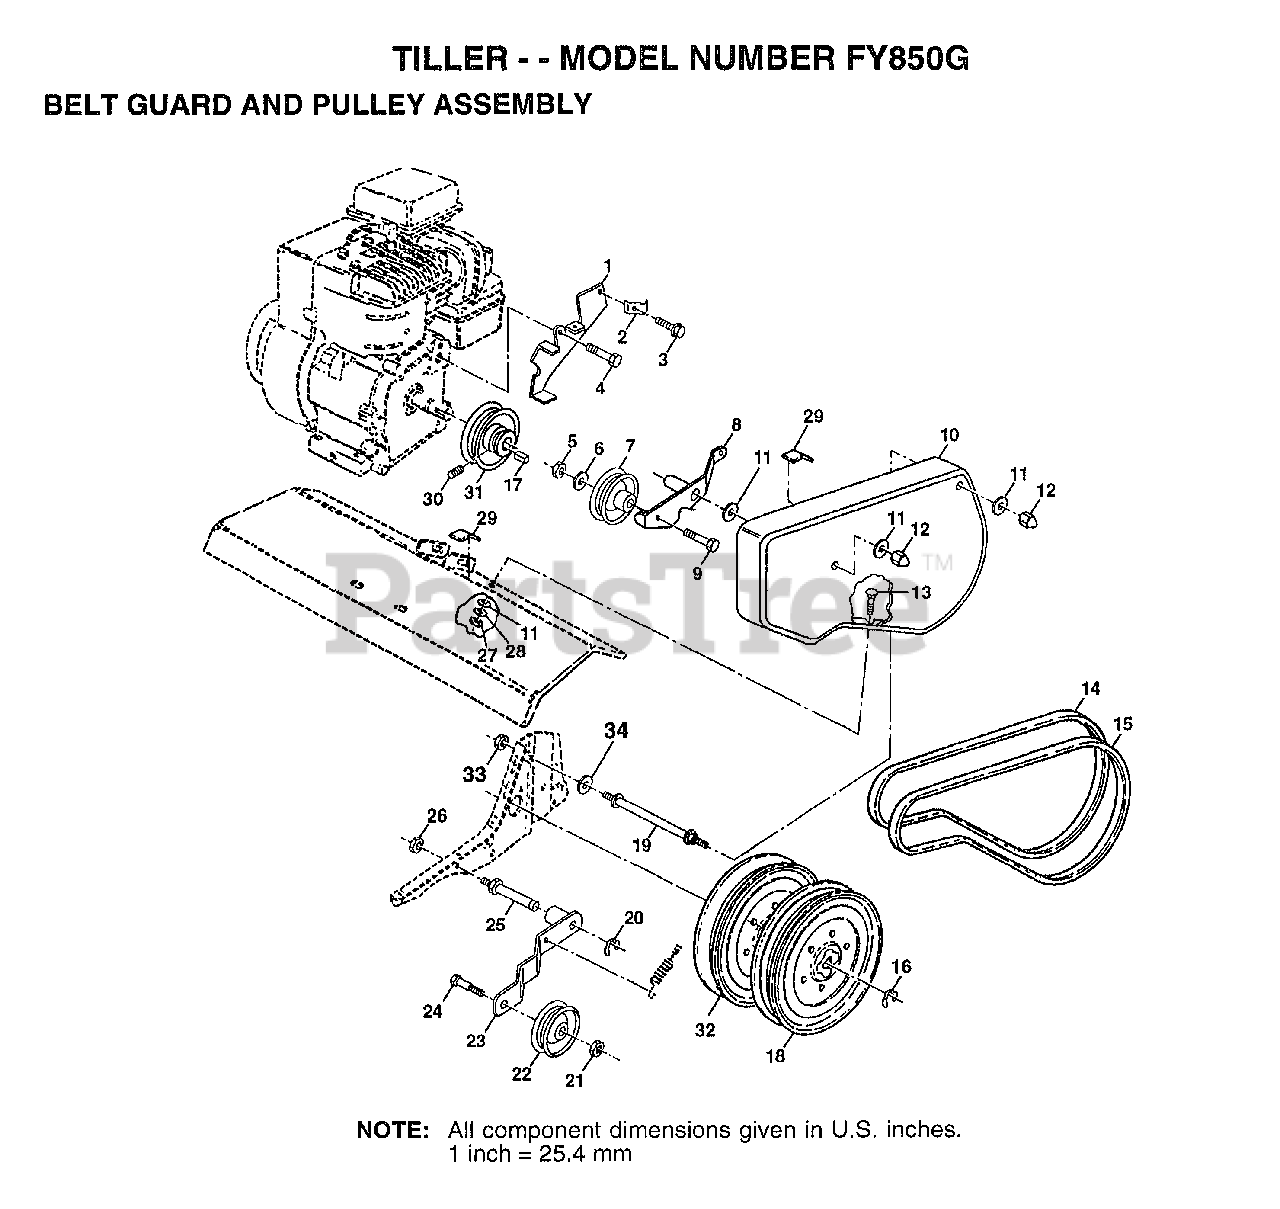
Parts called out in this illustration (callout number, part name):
1	ASM.BRKT.BELT.GRD
2	CONDIUT CLIP T
4	BOLT.HEX.HEAD
5	NUT.HEX.3/8-16UNC
6	WASHER
7	PULLEY W/SPACER
8	ARM.ASM.REV.IDLER
11	WASHER
12	NUT-CAP TI
13	BOLT T
14	BELT-V
17	KEY T
18	SHEAVE.TRANS
19	BOLT TI
20	KLIP RING TI
21	NUT
22	"PULLEY,IDLER"
23	"ARM, IDLER"
25	SHAFT IDLER TI
26	JAM NUT TI
28	LOCKWASHER
29	PAD IDLER TI
30	SET SCREW
31	ENGINE PULLEY TI
32	"SHEAVE,TRANS.""D"""
33	NUT
34	WASHER
